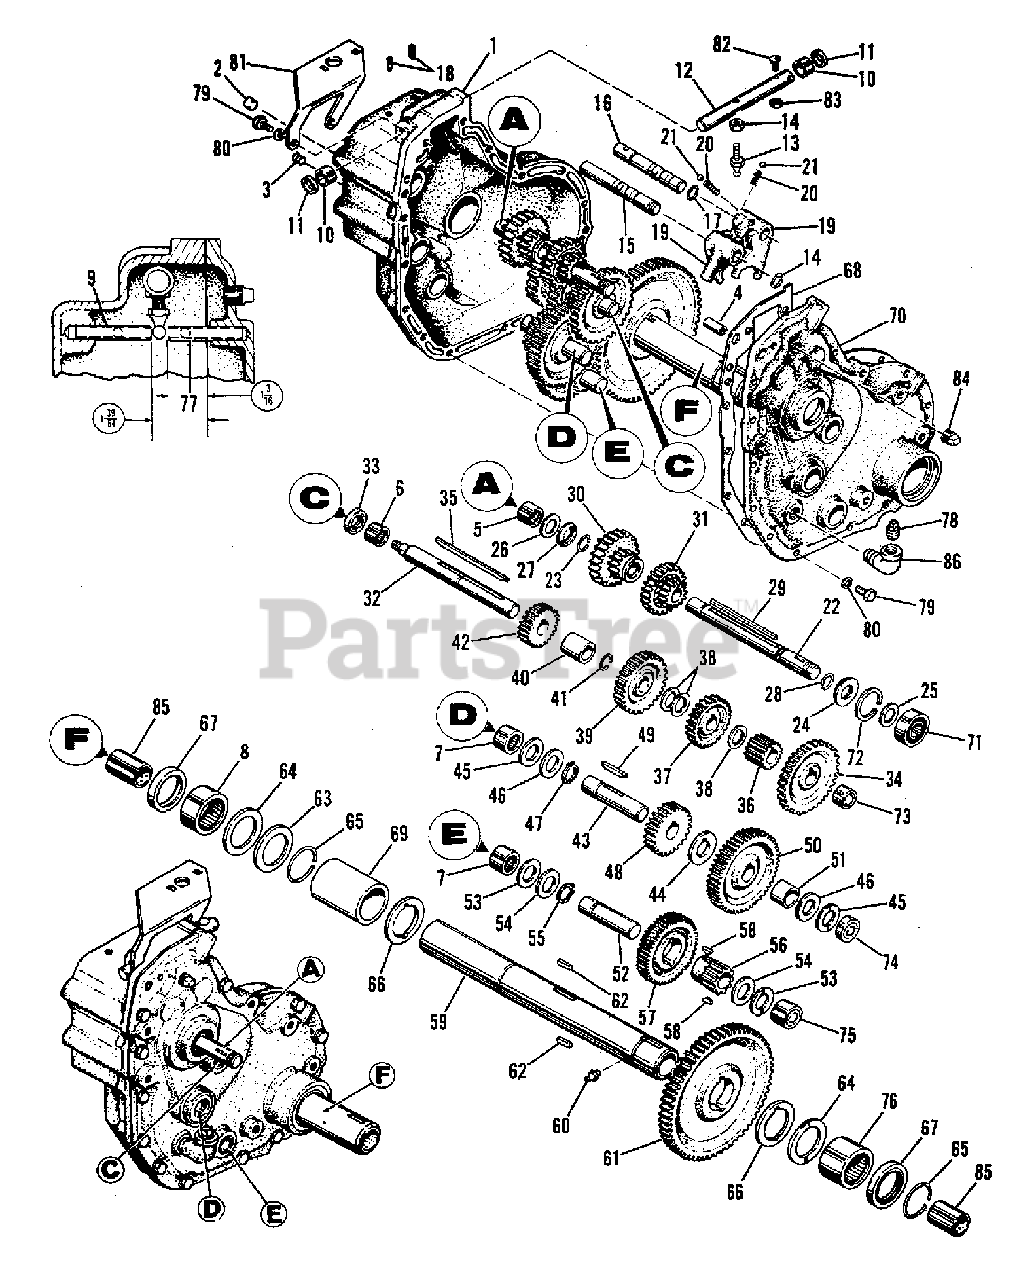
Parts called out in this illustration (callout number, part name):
1	CASE ASSEMBLY, Gear (Includes Items 2 Thru 7)
2	PLUG, Expansion
3	SETSCREW, 3/8NC x 3/8
4	PIN, Roll, 3/8 x 1
5	BEARING, Needle
6	BEARING, Needle
7	BEARING, Needle
8	BEARING, Needle
9	PIN ASSEMBLY, Roll
11	SEAL, Oil
12	ROD, Shift
13	STUD, Shift Stem (Prior S/N 29941001 & Up)
13	STEM, Shift (Efff. S/N 29941001 & Up)
14	NUT, Lock, 3/8NF (Prior S/N 29941001 & Up)
14	LOCKTITE, (Eff. S/N 29941001 & Up)
15	SHAFT, Reverse Medium
16	SHAFT, High, Low
17	RING, Retaining
18	SETSCREW, 5/16NC x 1/2
19	FORK, Shift
21	BALL, Shift Lock
22	SHAFT, Pulley
23	RING, Retaining
28	RING, Retaining
30	GEAR ASSEMBLY, II & IV
31	PINION ASSEMBLY, I & III
32	SHAFT, 1st Intermediate
33	SEAL, Oil
34	GEAR, Driven I
36	PINION, 1st Intermediate
37	PINION, Driven, III
38	SPACER, Gear
39	GEAR, Driven II
41	RING, Retaining
42	PINION, Reverse, IV
43	SHAFT, 2nd Intermediate
47	RING, Retaining
48	PINION, 2nd Intermediate
50	GEAR, 2nd Intermediate
52	SHAFT, 3rd Intermediate
55	RING, Retaining
56	PINION, 3rd Intermediate
57	GEAR, 3rd Intermediate
58	KEY, Woodruff
59	TUBE ASSEMBLY, Axle (w/ Bushing)
60	FITTING, Lube (Package Of 10)
61	GEAR, Drive
65	RING, Snap
66	WASHER, Axle Tube
68	GASKET, Gear Case
69	SPACER, Axle Tube
70	COVER ASSEMBLY, Gear Case (Includes Items 71 Thru 77)
72	RING, Retaining
73	BEARING, Needle
74	BEARING, Needle
75	BEARING, Needle
76	BEARING, Needle
77	PIN ASSEMBLY, Roll
78	PLUG, Pipe, 3/8
79	CAPSCREW, 5/16NC x 1
80	LOCKWASHER, 5/16
81	SUPPORT, Switch
82	BOLT, 5/16NC x 1
83	NUT, Jam, 5/16NC
84	PLUG, Pipe, 3/8
86	ELBOW, 3/8 x 90
